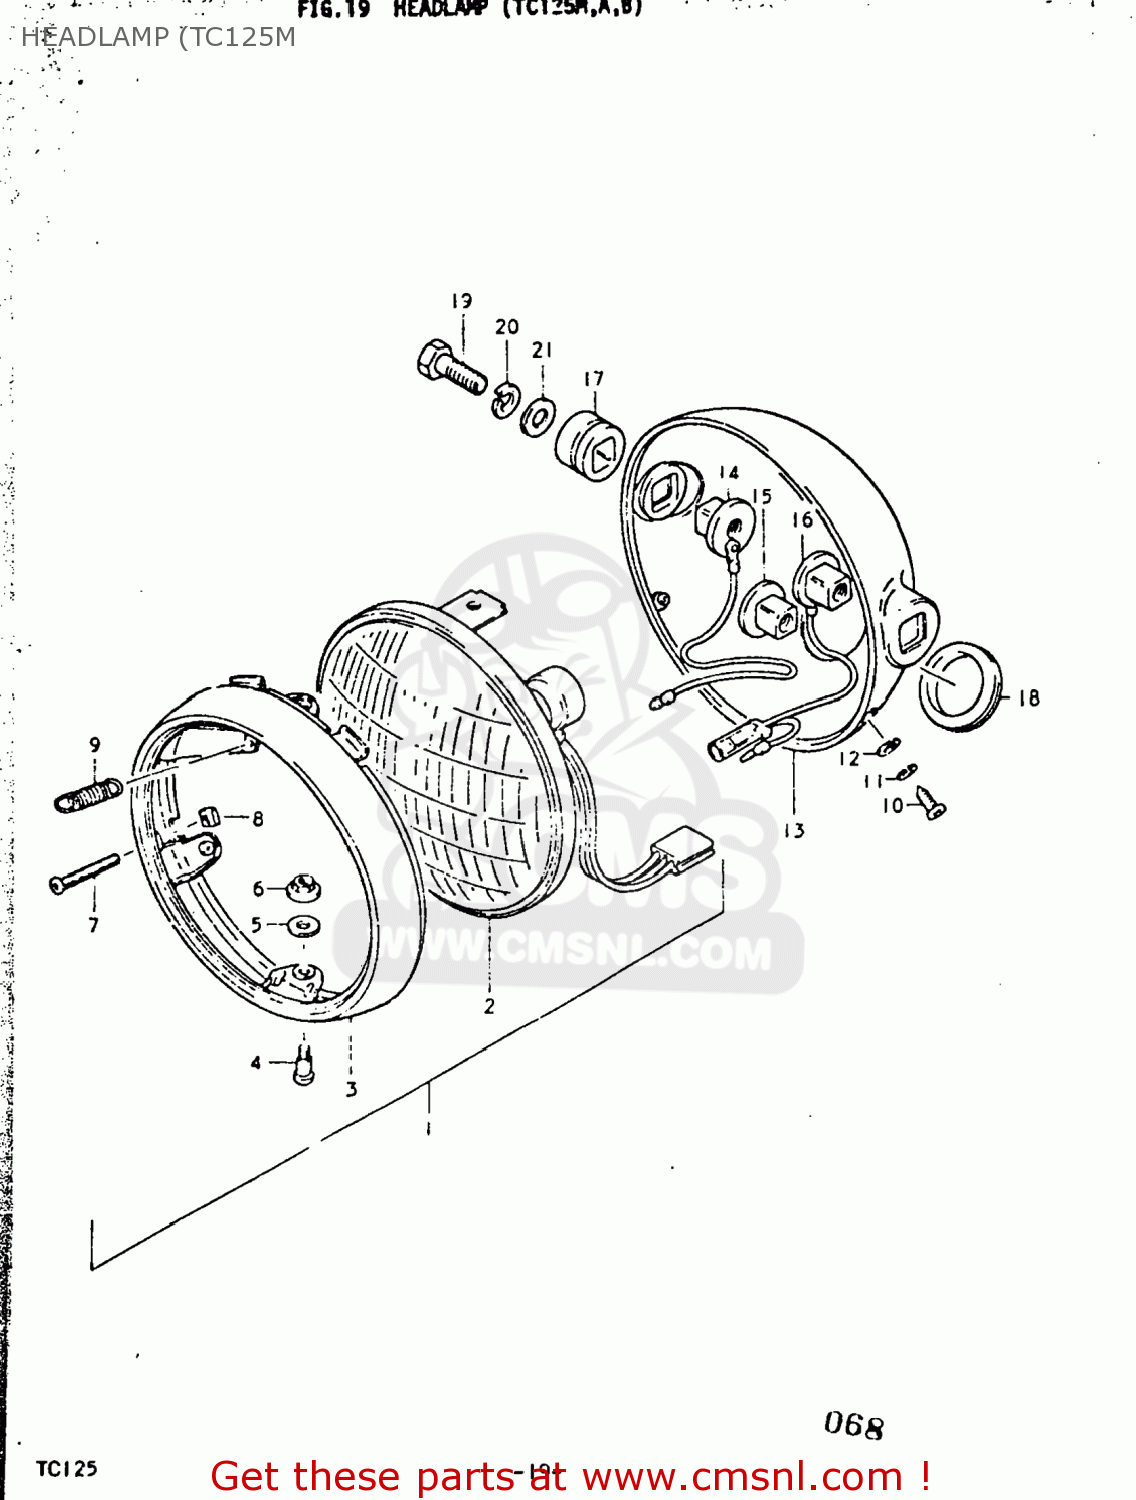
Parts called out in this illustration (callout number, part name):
1	HEADLAMP ASSEMBLY
2	LAMP UNIT
3	RIM,HEADLAMP
4	SCREW
5	SPACER,HEADLAMP UNIT
6	NUT,ADJUSTING
7	SCREW,HEADLAMP ADJUST
8	NUT,HEADLAMP ADJUSTER
9	SPRING,HEADLAMP ADJUST
10	SCREW
11	LOCK WASHER
12	WASHER
13	HOUSING COMP,HEADLAMP
14	SPACER,HEADLAMP HOUSING
15	SPACER,HEADLAMP HOUSING
16	SPACER,HEADLAMP HOUSING
17	CUSHION,HEADLAMP HOUSING
18	GROMMET,HEADLAMP HOUSING
19	BOLT
20	LOCK WASHER
21	WASHER 8MM
